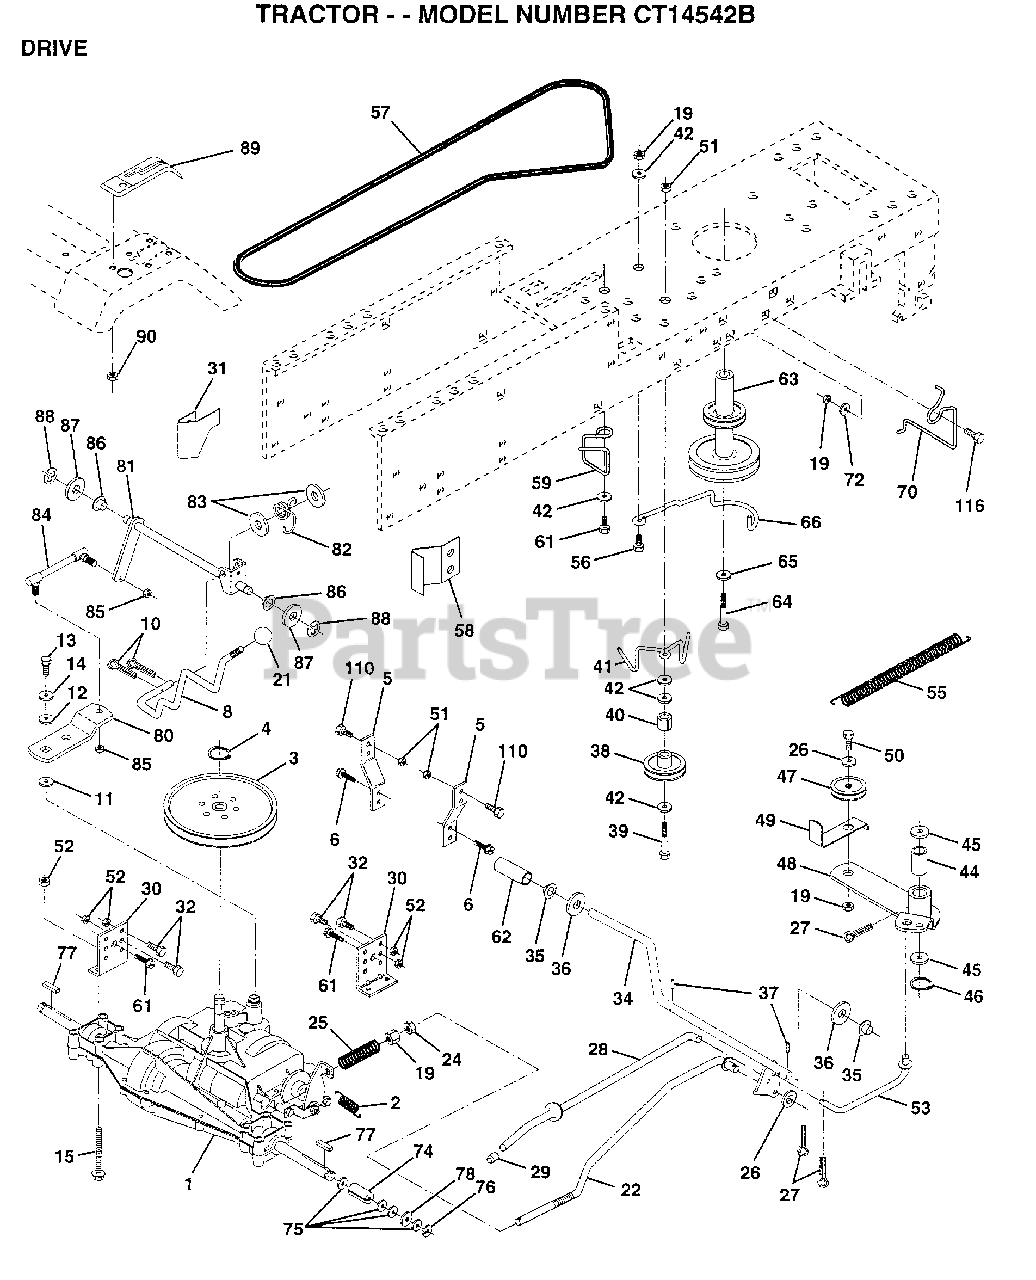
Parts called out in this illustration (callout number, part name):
2	SPRING.BRAKE.RETU
3	PULLEY TRANS
5	SPRING
6	SCREW
8	ROD SHIFT FEND LT
10	PIN COTTER 1/8
11	WASH-SHFT PLT LT
12	WASHER
13	BOLT.1/4-28.W/PAT
14	LOCKWASHER
15	BOLT.HX.FLG.5/16
19	NUT
21	CONTROL KNOB LT
22	BRAKE ROD
24	NUT
25	SPRING ROD LT
26	WASHER
27	COTTER PIN
28	ROD.BRAKE.PARK.LT
30	TRANSAXLE MTG BKT
31	"KEEPER,BELT LH T"
32	BOLT
34	SHAFT FOOT PEDAL
35	NYLON BEARING
36	WASHER LT
38	PULLEY.IDLER.FLAT
39	BOLT
40	SPACER T
41	KEEPER BELT
42	WASHER
44	"LY, BEARING"
45	WASHER LT
46	KLIP RING
48	ARM IDLER
49	RETAIN BELT
52	NUT
53	"LINK, CLUTCH T"
55	"SPRING, RETURN LT"
58	"KEEPER,BELT RH T"
59	KEEPER BELT CNTSP
61	SCREW
62	PEDAL COVER T
63	PULLEY.ENGINE
64	BOLT
65	LOCKWASHER
70	KEEPER BELT ENG
72	WASHER
74	SPACER LT
75	WASHER
76	E-RING LT
77	SQUARE KEY
78	WASHER
80	ARM SHIFT TRANS
81	SHAFT ASM.SHIFT
82	"SPRING,TORSION"
83	WASHER
84	TIE ROD
85	NUT.CNT.LOCK.1/4
86	BUSHING
87	WASHER D
88	KLIP RING
90	NUT
116	BOLT RDHD 3/8-16
